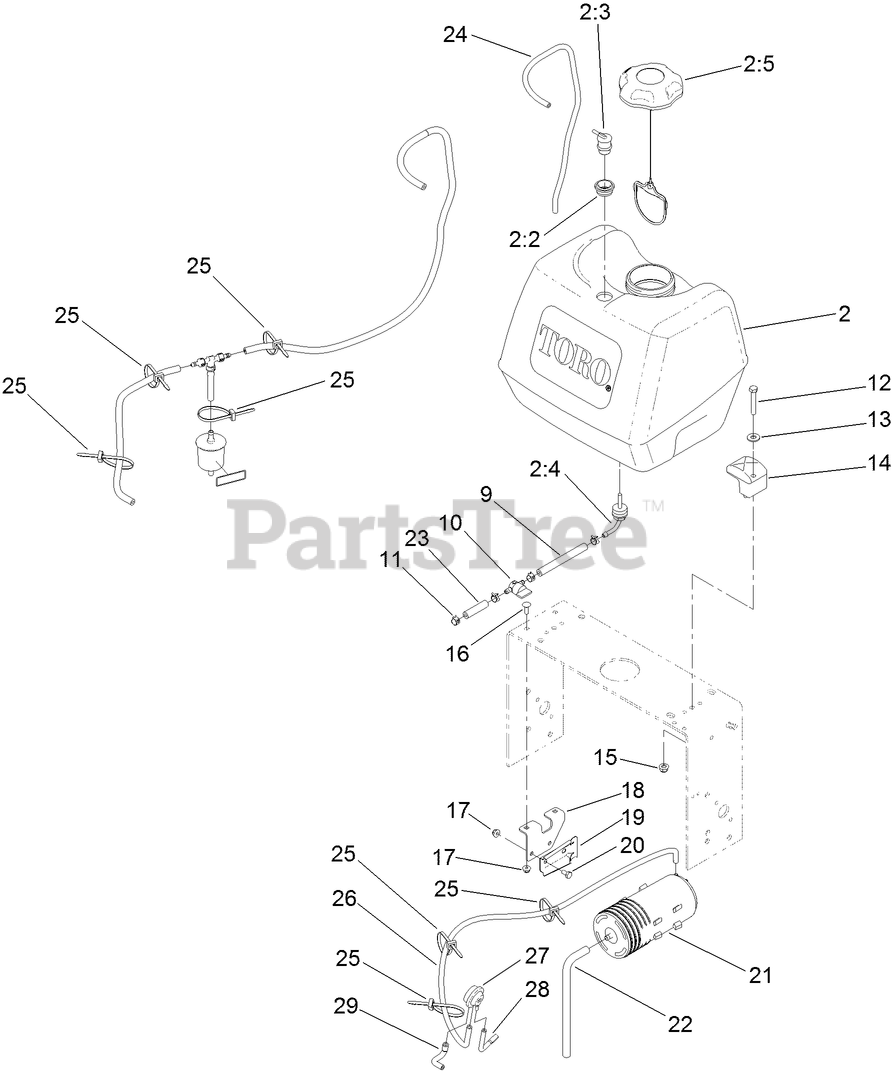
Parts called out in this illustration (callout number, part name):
2	FUEL TANK ASM
2:2	GROMMET
2:3	VALVE-VENT, FUEL
2:4	FITTING-FUEL, BULKHEAD
2:5	CAP-FUEL, RATCHETING
9	HOSE-FUEL
10	VALVE-FUEL
11	CLAMP-HOSE
12	SCREW-HH
13	WASHER-FLAT
15	NUT-HF, NI
16	BOLT-CARR
17	NUT-HF
18	BRACKET-CANISTER, CARBON
19	BRACKET-CANISTER, CARBON
20	SCREW-HH
21	CANISTER-CARBON, 800CC
22	HOSE-VENT, CANISTER
23	HOSE-FUEL
24	HOSE-VENT
25	TIE-CABLE
26	HOSE-VENT, FORMED
27	VALVE-CONTROL, VACUUM
28	HOSE-VENT, FORMED
29	HOSE-VENT, FORMED
